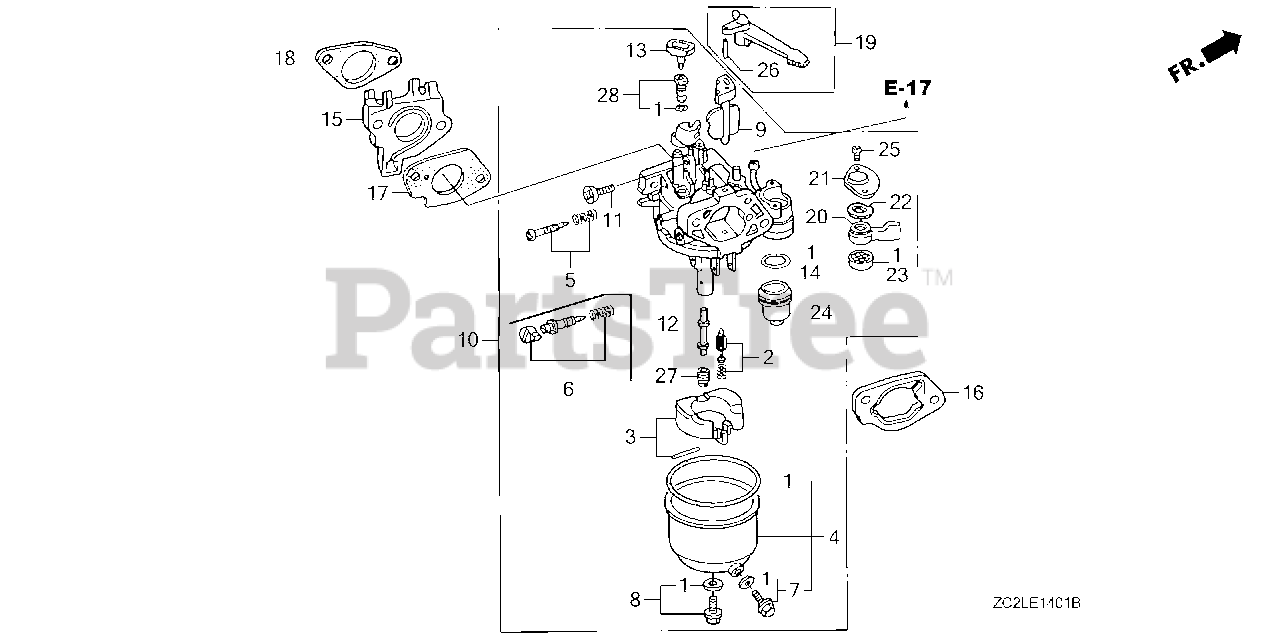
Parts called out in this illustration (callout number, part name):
1	GASKET SET (INCLUDES 16173-001-004)
2	VALVE SET, FLOAT
4	CHAMBER SET, FLOAT
6	SCREW SET, PILOT
7	SCREW SET, DRAIN
8	SCREW SET
10	CARBURETOR ASSY. (BE80D B/C)
11	SCREW, THROTTLE STOP
12	NOZZLE, MAIN
13	COLLAR, SETTING
14	GASKET, FUEL STRAINER CUP
15	INSULATOR, CARBURETOR
16	SPACER, CARBURETOR
17	GASKET, CARBURETOR
18	GASKET, INSULATOR
19	LEVER, CHOKE (STD)
20	LEVER, PETCOCK
21	PLATE, LEVER SETTING
22	SPRING, PETCOCK LEVER
23	GASKET, PETCOCK
24	CUP, FUEL STRAINER
25	SCREW, PAN (3X6)
26	PIN, SPRING (2X12)
27	JET, MAIN (#90)
27	JET, MAIN (#92)
27	JET, MAIN (#95)
28	JET SET, PILOT (#35)
